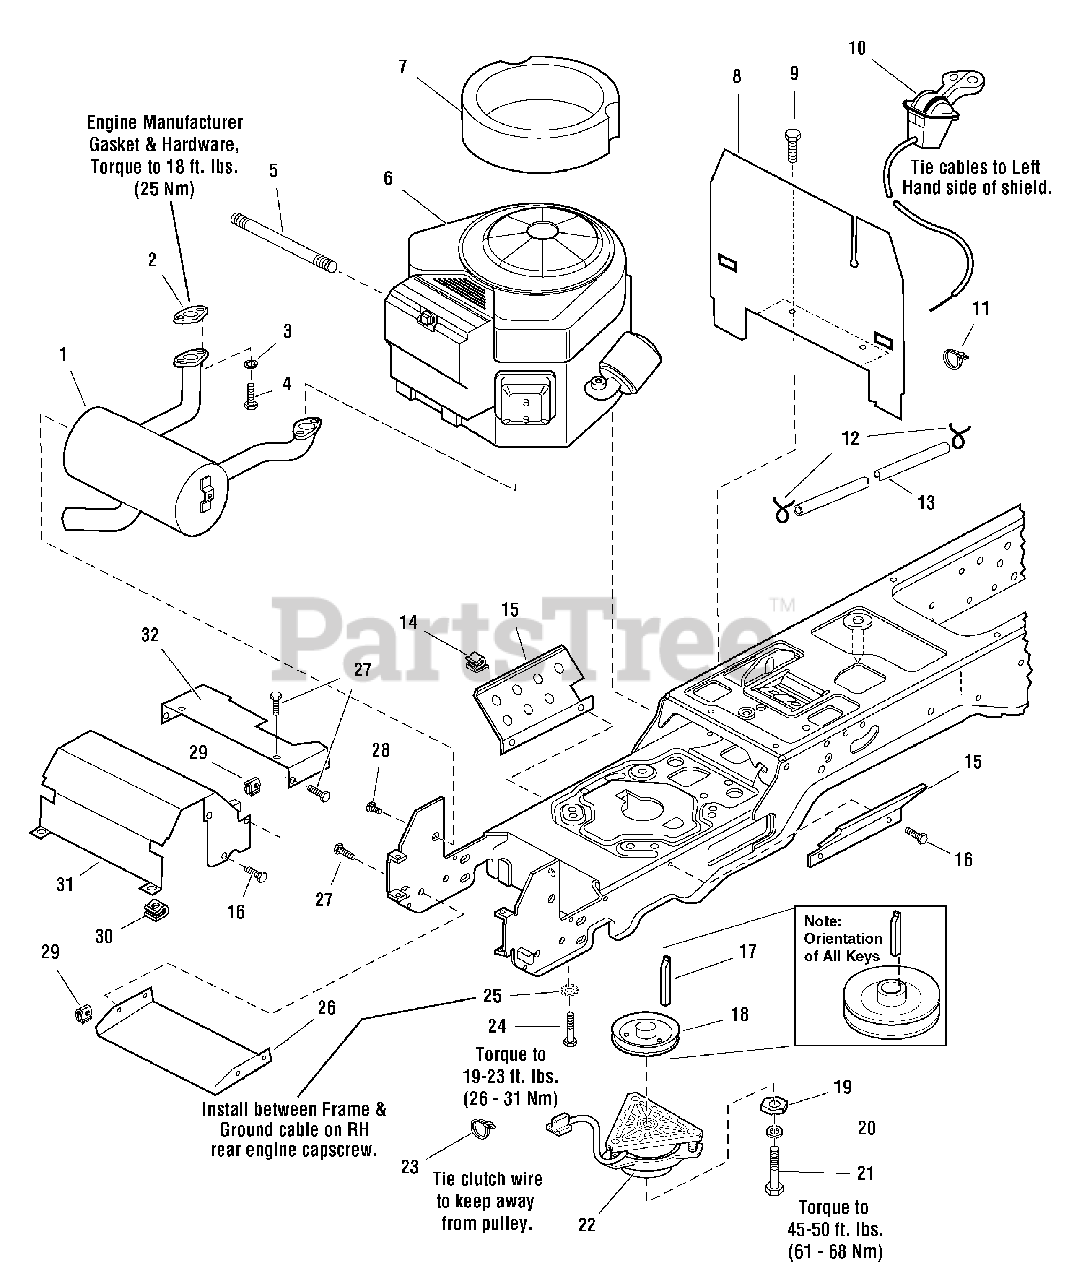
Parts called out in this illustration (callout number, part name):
1	MUFFLER
2	GASKET
3	LOCKWASHER, 5/16
4	CAPSCREW, Socket Head, 5/16-18 x 7/8, G8
5	HOSE, Oil Drain
6	*ENGINE, 20HP Briggs & Stratton VANGUARD Twin
6	*ENGINE, 21HP Briggs & Stratton VANGUARD Twin
6	*ENGINE, 22HP Briggs & Stratton VANGUARD Twin
6	*ENGINE, 23HP Briggs & Stratton VANGUARD Twin
7	SEAL, Circle
9	CAPSCREW, Hex Head Taptite, 1/4-20 x 1/2
10	CONTROL, Throttle Double 39" Long w/Knobs
10	CONTROL, Throttle Double
12	CLAMP, Hose Type E
13	HOSE, 59" Long
14	CLIP, Wire
16	CAPSCREW, Hex Head Taptite, 1/4-20 x 3/8
18	PULLEY & HUB ASSEMBLY, 4-1/2 OD
19	WASHER, Hex
20	LOCKWASHER, 7/16
21	CAPSCREW, Hex Head, 7/16-20 x 2-3/4
22	CLUTCH, Electric, OGURA
22	CLUTCH, Electric, Big Brake OGURA
24	CAPSCREW, Hex Head Taptite, 3/8-16 x 1-1/2
25	LOCKWASHER, External Tooth, 3/8
26	SHIELD, Muffler Bottom
27	CAPSCREW, Hex Head Flange Lock, 1/4-20 x 5/8
28	CAPSCREW, Hex Head Taptite, 5/16-18 x 1/2
29	NUT, Speed, 1/4-20
30	NUT, Speed, 5/16-18
31	DUCT, Muffler Top
32	DUCT, Muffler Extension
